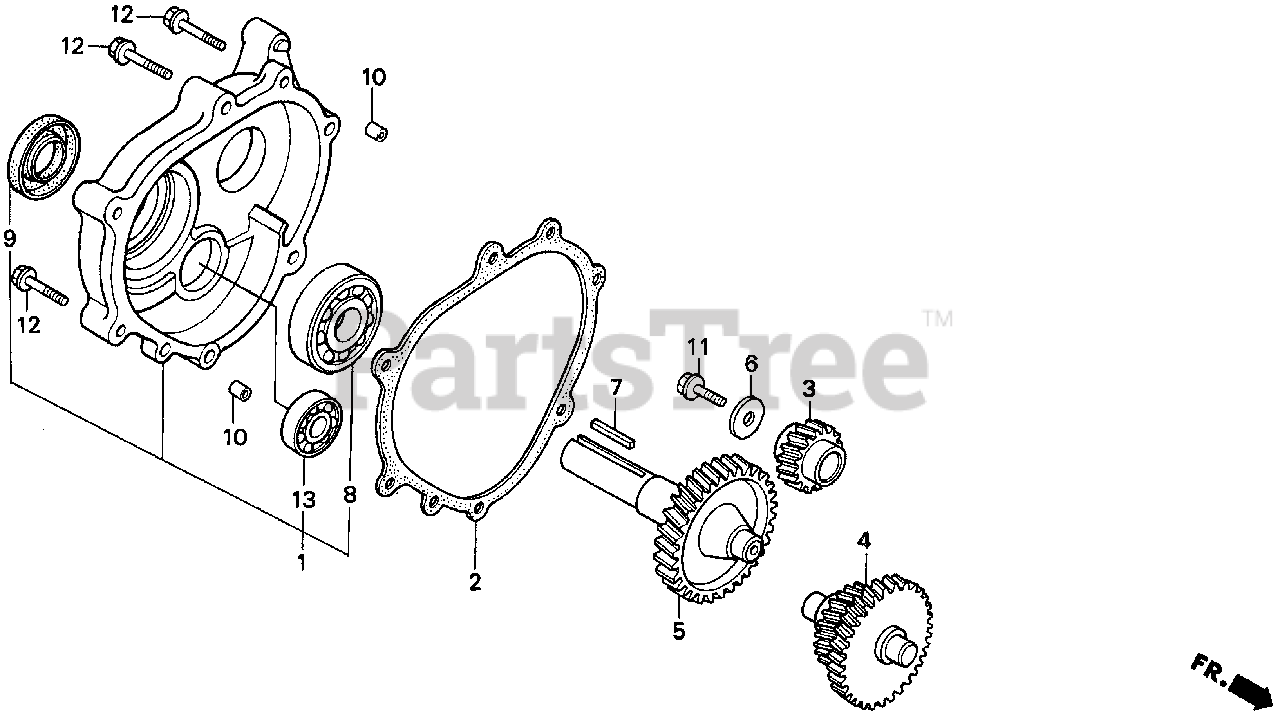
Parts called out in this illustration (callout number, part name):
1	COVER ASSY., GEAR CASE (H-TYPE)
2	GASKET, CHAIN CASE COVER
3	GEAR, PRIMARY DRIVE (12T)
4	COUNTERSHAFT
5	SHAFT, P.T.O. (HQ-TYPE)
6	WASHER (8MM)
7	KEY (6.3X6.3X43)
8	BEARING, RADIAL BALL (6206) (NTN CORP.)
9	OIL SEAL (30X46X8)
10	PIN A, DOWEL (8X14)
11	BOLT, FLANGE (8X25)
12	BOLT, FLANGE (8X40)
13	BEARING, RADIAL BALL (6302)
